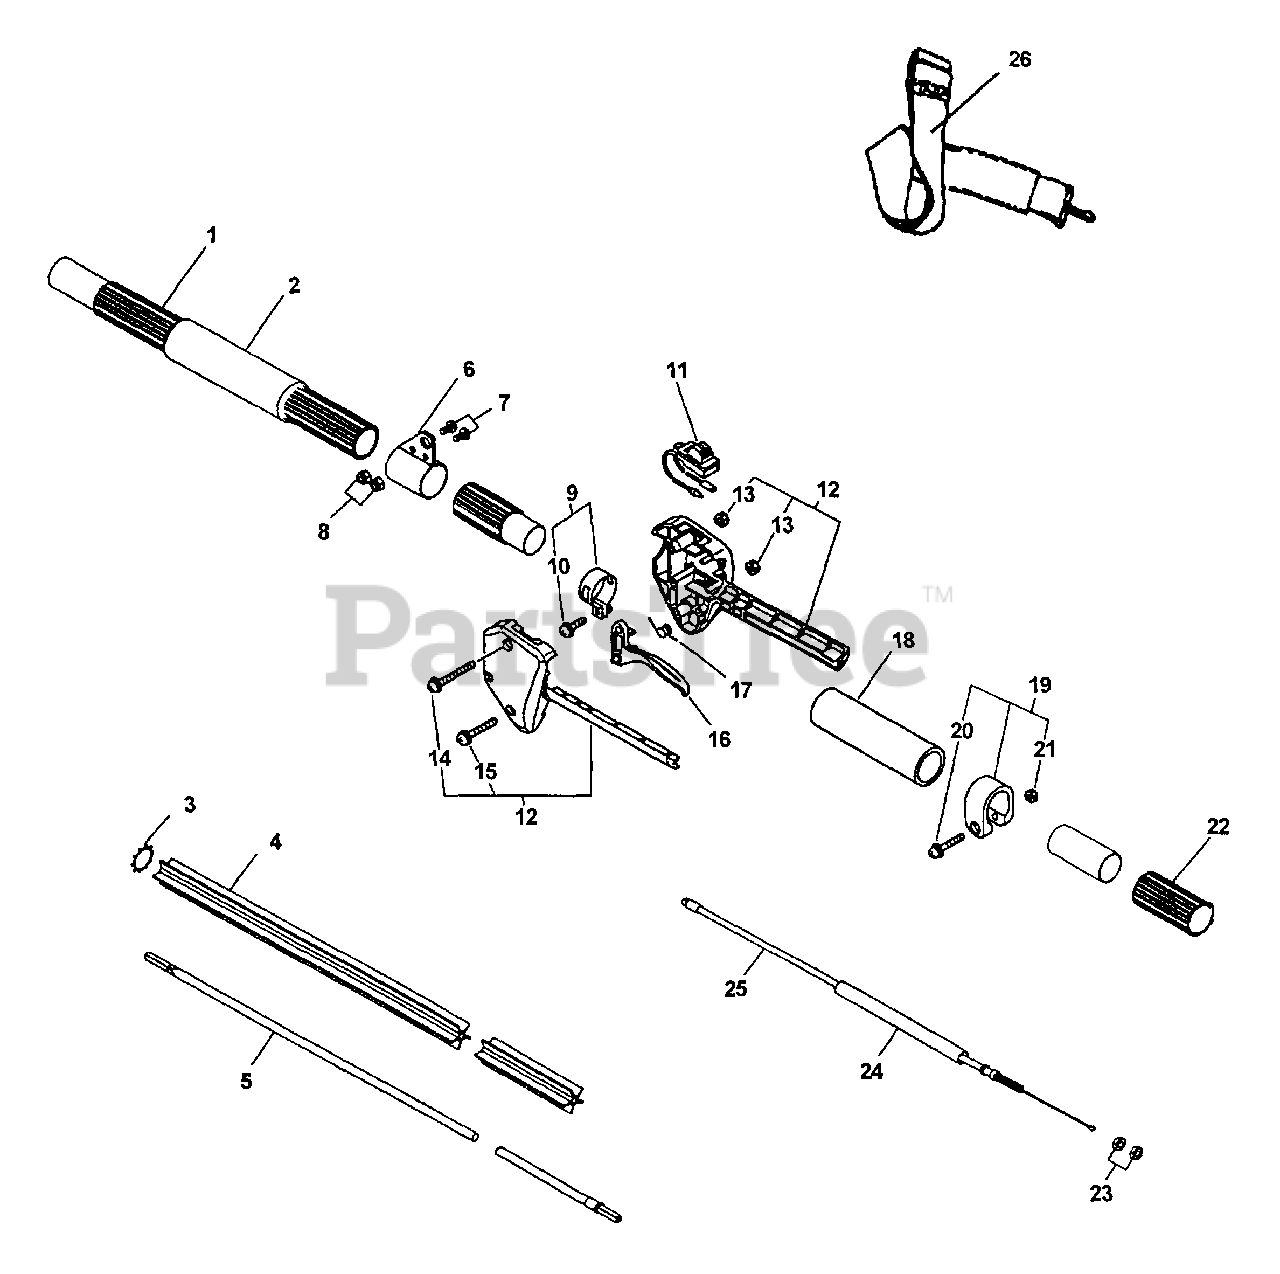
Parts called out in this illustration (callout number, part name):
1	MAIN PIPE ASSY
2	GRIP, HANDLE
4	LINER - FLEXIBLE
5	DRIVESHAFT - FLEXIBLE
6	HANGER KIT
7	SCREW
8	NUT, LOCK 10-24 UNC
9	CLAMP KIT
10	SCREW 5×14
11	SWITCH ASSY, ON-OFF
12	HANDLE KIT, CONTROL
13	NUT M5
14	SCREW 5×35
15	SCREW 5×25
16	TRIGGER, THROTTLE
17	SPRING, TORSION
18	GRIP, HANDLE
19	CLAMP KIT
20	SCREW 5×28
21	NUT M5
22	SLEEVE, HOUSING 2-5/8"
25	CABLE, THROTTLE
26	STRAP ASSY, SHOULDER
